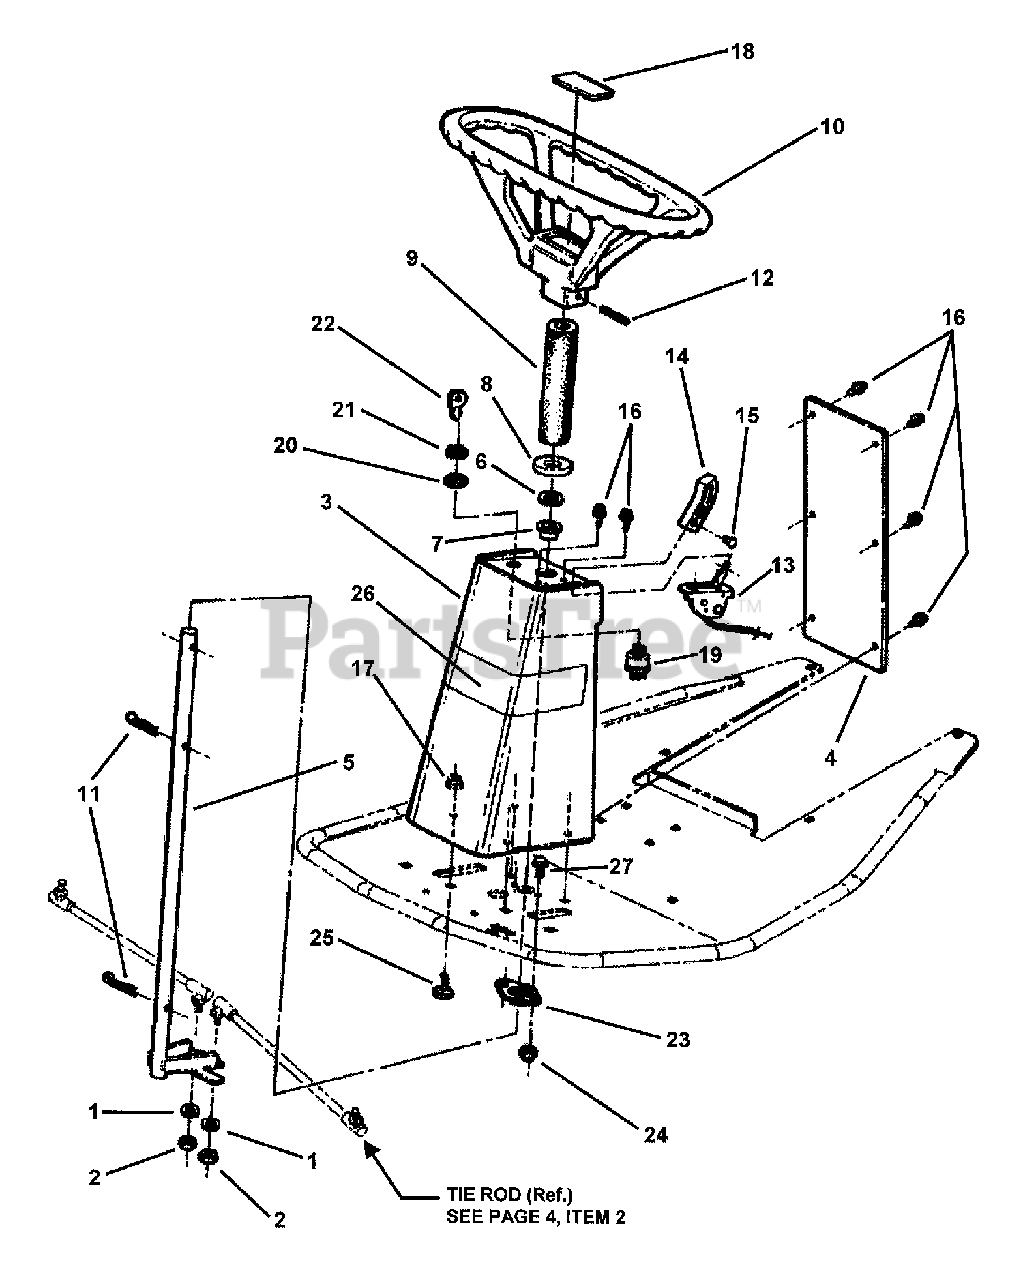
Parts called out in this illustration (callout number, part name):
1	WASHER, 5/16 Split Lock
2	NUT, 5/16-24 Hex, Grade 5
3	WELDMENT, Steering Column
4	COVER PLATE, Steering Column
5	WELDMENT, Steering Shaft
6	WASHER, 3/4" I.D. x 1-1/8" O.D. x 1/16" Thick Flat
7	BEARING, Nylon
8	COVER, Steering Shaft
9	FOAM COVER, Steering Shaft (6-1/8" Long)
9	FOAM COVER, Steering Shaft (8-1/4" Long)
10	ASSEMBLY, Steering Wheel
11	PIN, 5/32 x 1" Cotter
12	PIN, 1/4 x 1-1/2" Roll
13	CABLE, Throttle
14	KNOB, Throttle
15	RIVET, Plastic Snap
16	SCREW, #10-24 x 1/2" Hex Washer Self-Tap (Torx)
17	NUT, 5/16-18 Hex Flange Lock, Grade 5
18	DECAL, Snapper (Steering Wheel)
19	SWITCH, Ignition
20	WASHER, 5/8" Internal Tooth Lock
21	NUT, 5/8-32 Special Hex
22	KEY (Pair)
23	BEARING, .75 I.D. PM Flange
24	NUT, 1/4-20 Hex Nyloc
25	BOLT, 5/16-18 x 3/4" Short Neck Carriage, Grade 5
26	DECAL, Steering Column
27	SCREW, 1/4-20 x 3/4" Hex Head Cap, Grade 5
